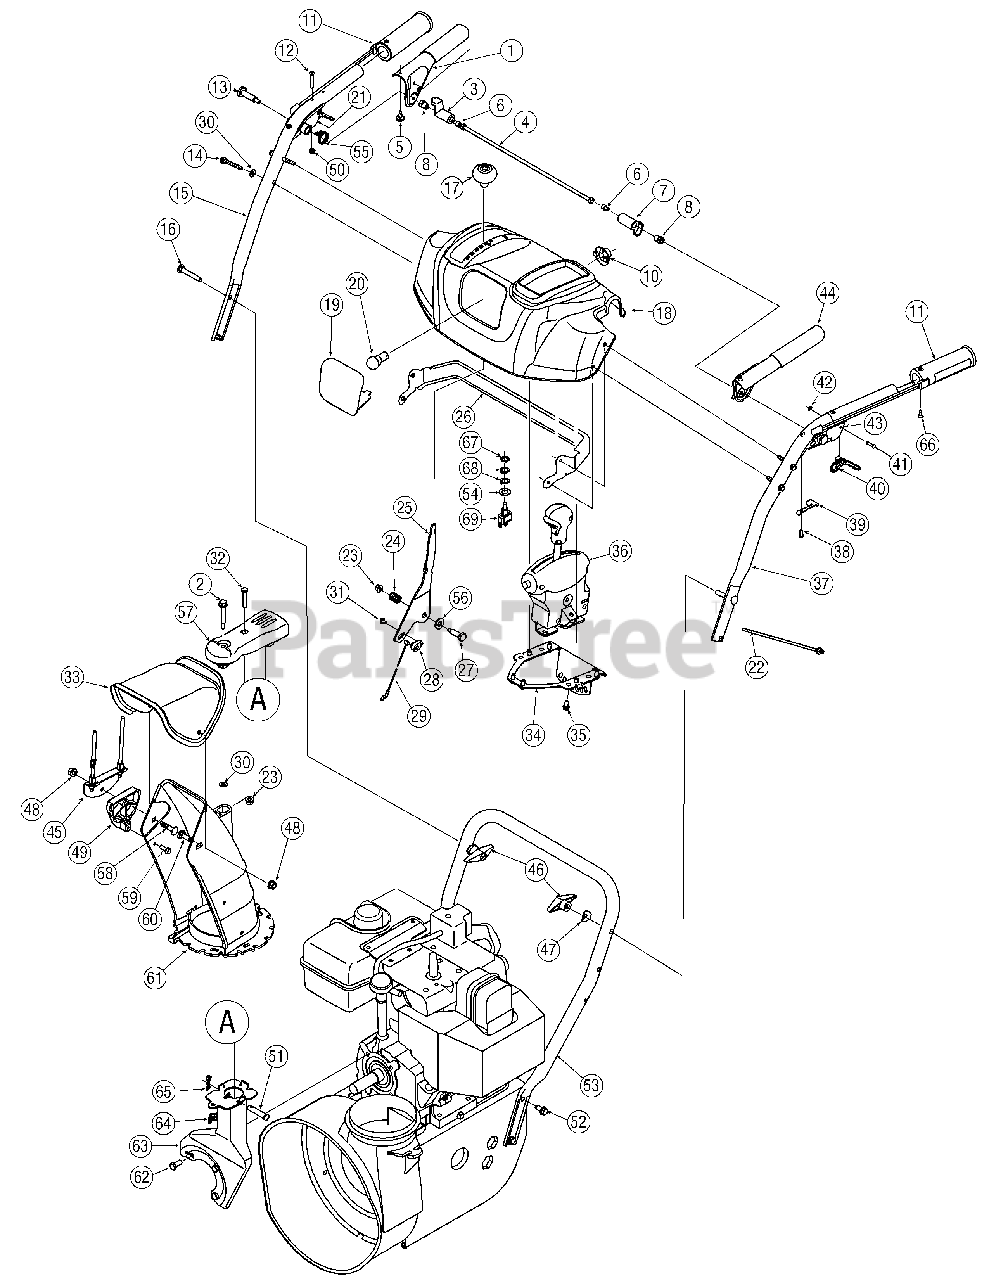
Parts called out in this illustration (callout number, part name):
1	Handle Engagement Assembly
2	Flange Shoulder Screw
3	Lock Plate
4	Pivot Rod
5	Rubber Bumper
6	Screw, 1/4-20 x.375
7	Clutch Lock Cam
8	Shoulder Nut, 1/4-20
10	Light Socket
11	Heated Handle Grip
12	Screw, #10-24 x 0.375
13	Shoulder Screw, 1/4-20 x 1.345
14	Screw, 1/4-20 x 1.750
16	Carriage Screw, 5/16-18 x 2
17	Shift Knob
18	Handle Panel (Includes Ref.#19)
20	Lamp
21	Handle Clutch Lock - RH
22	Cable Tie
23	Flange Lock Nut, 1/4-20
24	Compression Spring
28	Cable Barrel Holder
29	Speed Selector Cable
30	Flat Washer, .25 x .630 x.0515
31	Screw, #10-16 x .500
32	Hex Screw, 1/4-20 x 1.50
33	Upper Chute
35	Hi-Lo Screw, 1/4-15 x 0.5
36	4-Way Chute Control™ (Includes Ref.# 57)
38	Screw, #8-16 x 0.50
39	Clutch Lock Spring
40	Steering Control
43	Handle Clutch Lock - LH
44	Handle Engagement Assembly LH
46	Handle Knob Assembly
47	Saddle Washer
48	Flange Lock Nut, 5/16-18
49	Chute Tilt Cable Guide
50	Hex Lock Nut, #10-24
52	AB Screw, 5/16-18 x 0.75
54	Flat Washer, .474 x .879 x .064
55	Torsion Spring
56	Flat Washer
58	Carriage Bolt, 5/16-18 x 1.50
59	Hi-Lo Screw, 1/4-15 x .75
60	Carriage Bolt, 5/16-18 x 1.0
61	Lower Chute
62	Hex Screw, 5/16-24 x .750
65	Bow Tie Cotter Pin
66	AB Screw, #10-16 x .625
68	Toggle Switch Lock Ring
69	Toggle Switch
